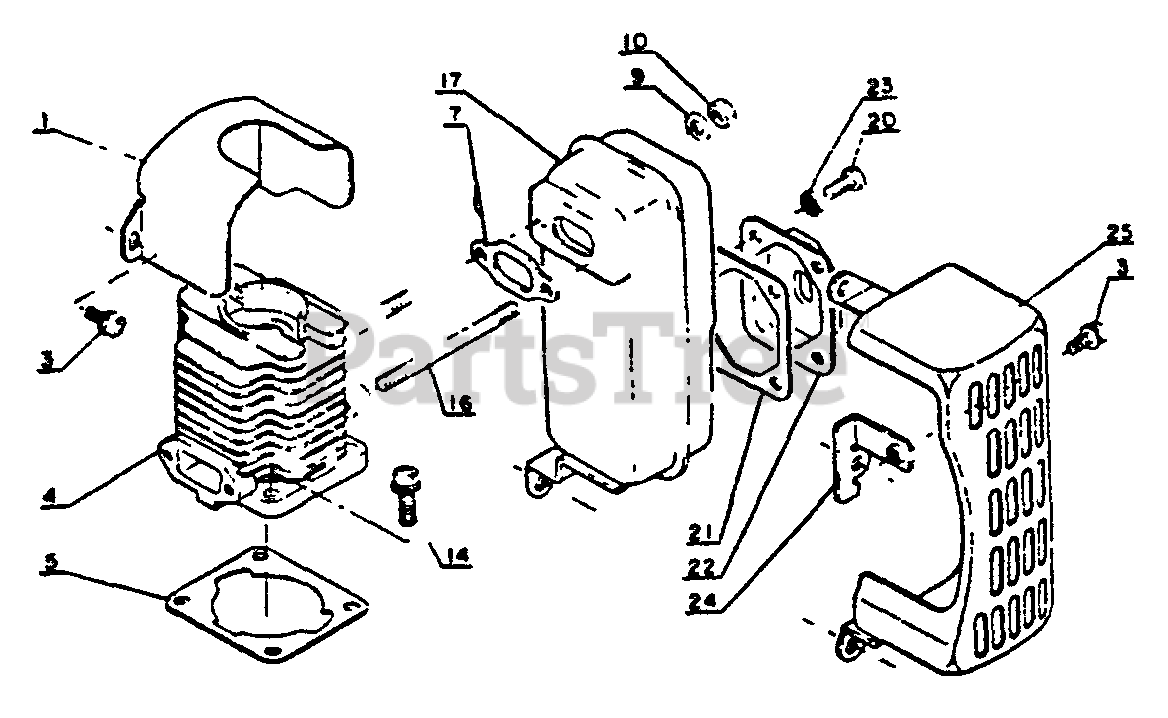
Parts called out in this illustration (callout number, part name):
1	SHIELD, CYLINDER
3	SCREW - 4X10
4	CYLINDER
5	GASKET, CYLINDER
7	GASKET, EXHAUST
9	WASHER - 5
10	LOCKNUT - 5
14	SCREW - 5X18
17	MUFFLER
20	SCREW - 4X10
21	GASKET, EXHAUST
22	GUIDE, EXHAUST
23	LOCKWASHER - 4
24	Supporter
25	COVER, MUFFLER
